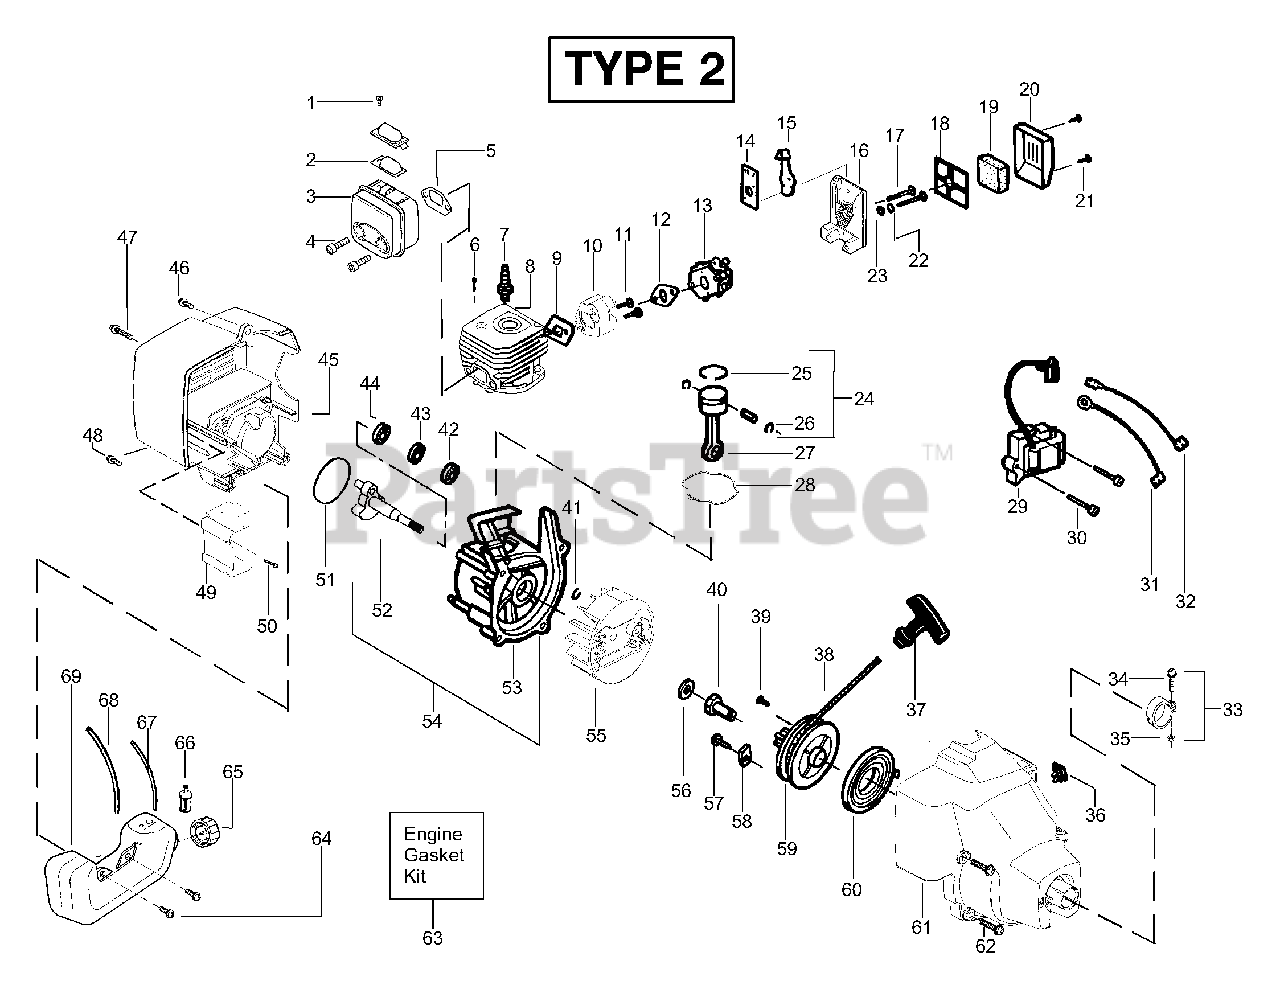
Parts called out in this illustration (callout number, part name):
1	Screw-Screen
2	Kit-Spark Arrestor
3	Kit-Muffler
4	Bolt-Muffler
5	Gasket-Muffler (kit)
6	Screw-Cylinder
7	Spark Plug (RCJ 6Y)
8	Kit-Cylinder
9	Gasket-Cyl./Carb.(kit)
10	Adapter-Carb.
12	Gasket-Carb. (kit)
13	Kit-Carburetor Ass'y (C1U-W10B)
14	Choke Plate Mounting
15	Shutter-Choke
18	Plate-Filter Support
19	Foam-Air Filter
20	Cover-Air Filter
22	Spacer-Choke
24	Kit-Piston
25	Piston Ring
26	Retainer-Piston Pin
27	Assy-Connecting Rod
28	Seal-Cylinder (kit)
29	Ignition Module
31	Assy-Ground Wire
32	Assy-Leadwire
33	Assy-Nose Cone Clamp
34	Screw-Nose Cone
35	Nut-Nose Cone
36	Kit-Switch
37	Handle-Starter
38	Kit-Rope
40	Coupling-Drive
41	Retain. Ring-C'shaft
42	Outer Bearing
43	Kit-C'case Seal
44	Inner Bearing
45	Shroud-Rear
47	Screw
49	Shield-Heat
50	Screw
51	O-Ring-C'case (kit)
52	Assy-Crankshaft
53	Assy-Crankcase
54	Assy-C'case & C'shaft
55	Assy-Flywheel
56	Washer-Flat
58	Retainer-Can
59	Kit-Starter Pulley
60	Spring-Starter
61	Assy.-Fan Hsg
62	Screw
63	Kit-Engine Gasket
64	Retainer
65	Assy-Fuel Cap
66	Assy-Fuel Pickup
67	Kit-Fuel Line (Small)
68	Kit-Fuel Line (Large)
69	Assy-Fuel Tank
